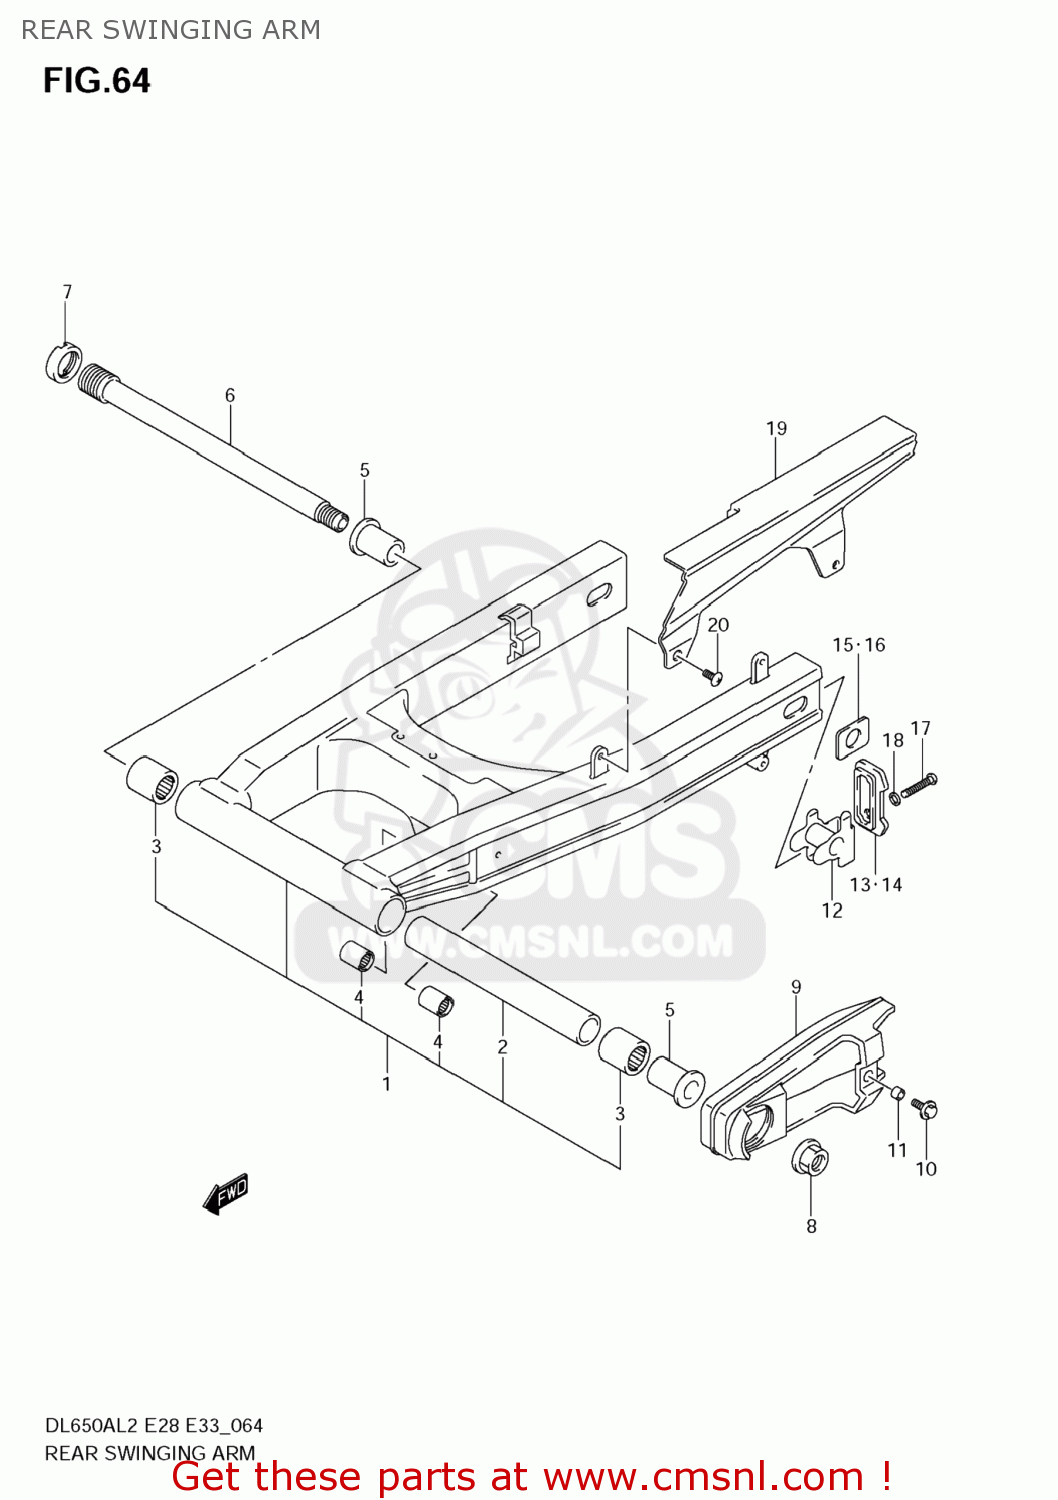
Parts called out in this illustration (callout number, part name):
1	SWINGINGARM ASSY,RR
2	SPACER(20.8X27.2X196.7)
3	BEARING(25X33X35)
4	BEARING(17X24X25)
5	SPACER,RR SWGARM PIVOT BERRING
6	SHAFT,RR SWINGINGARM PIVOT
7	NUT,RR SWGARM PIVOT BOLT
8	NUT
9	BUFFER,CHAIN TOUCH DEFENSE
10	BOLT(6X20)
11	SPACER(6.5X10X7)
12	ADJUSTER,CHAIN
13	PLATE,CHAIN ADJUSTER GUIDE,R
14	PLATE,CHAIN ADJUSTER GUIDE,L
15	WASHER,CHAIN ADJUSTER
16	WASHER,CHAIN ADJUSTER
17	BOLT(8X50)
18	WASHER
19	CASE,CHAIN
20	SCREW(6X16)
